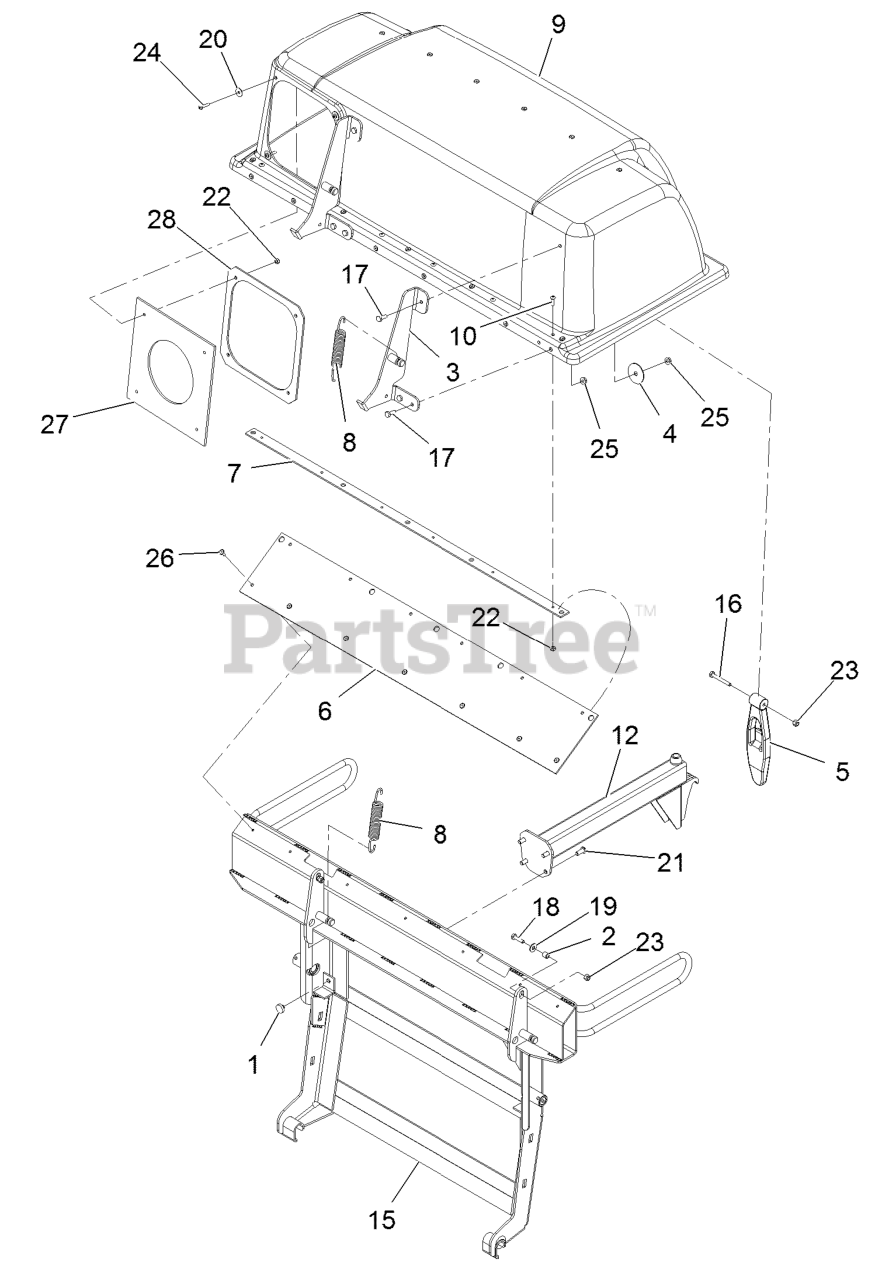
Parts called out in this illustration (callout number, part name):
3	Hinge ASM
7	Plate-Backing
8	Spring-Extension
9	Hood Assembly - Service Only
10	Screw-Truss Head #10-24 X 3/4
12	Bag Support ASM
15	Frame-Bag, Twin
16	Screw-HH 1/4-20 X 2
17	Screw-HH 1/4-20 X 3/4
18	Screw-HH 1/4-20 X 1
19	Washer-1/4 Std
21	Screw-Button Head 5/16-18 X 3/4
22	Nut-Nyloc #10-24
23	Nut-Nyloc 1/4-20
24	Screw-PPH #10-24 X 7/8
25	Nut-Whizlock 1/4-20
27	Seal-Chute
28	Clamp-Seal
